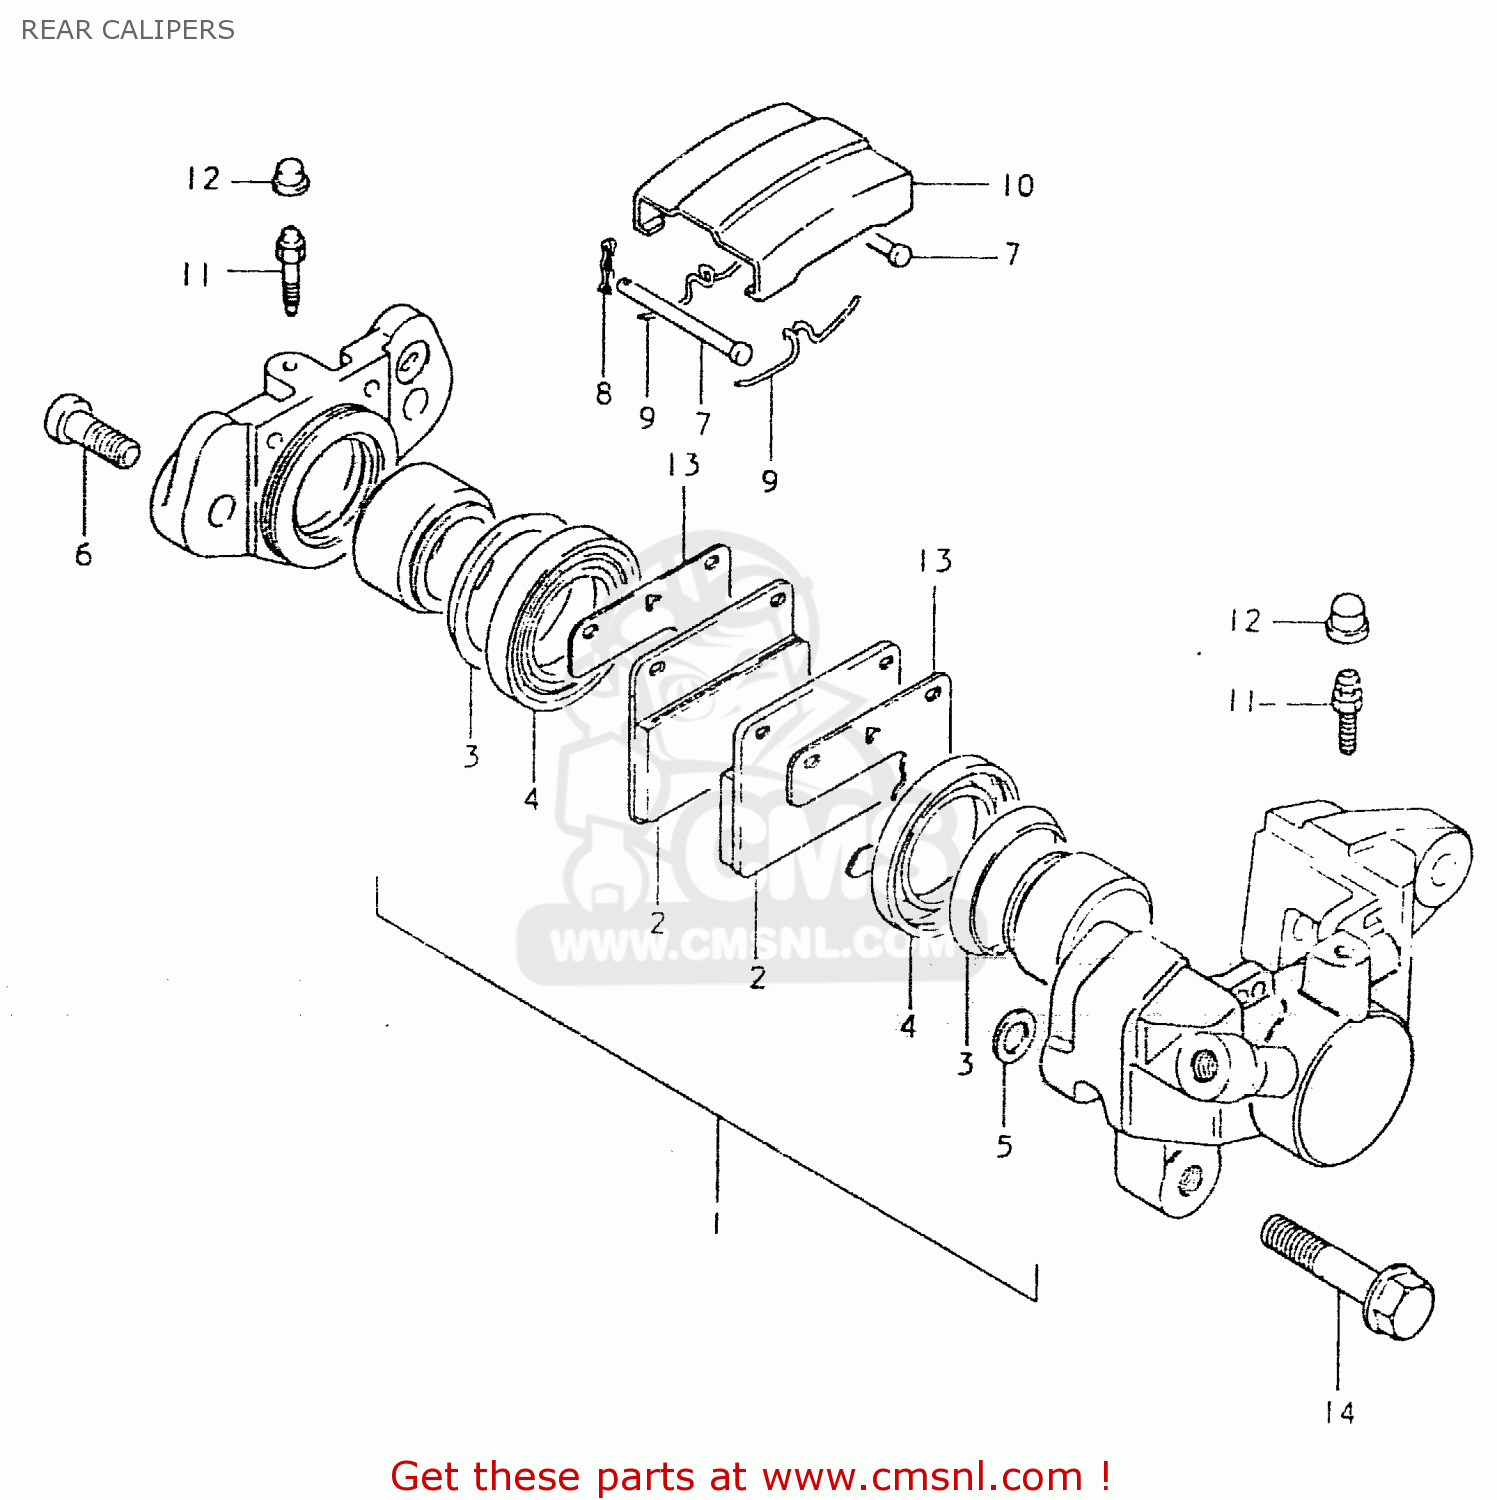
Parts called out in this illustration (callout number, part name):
1	PISTON SET
2	PAD,BRAKE
3	SEAL,PISTON
4	BOOT,PISTON
5	SEAL,PISTON
6	BOLT,HOUSING
7	PIN,PAD
8	CLIP,PAD PIN
9	SPRING
10	COVER,DUST
11	BLEEDER
12	CAP,BREATHER
13	SHIM,RR CALIPER
14	BOLT
